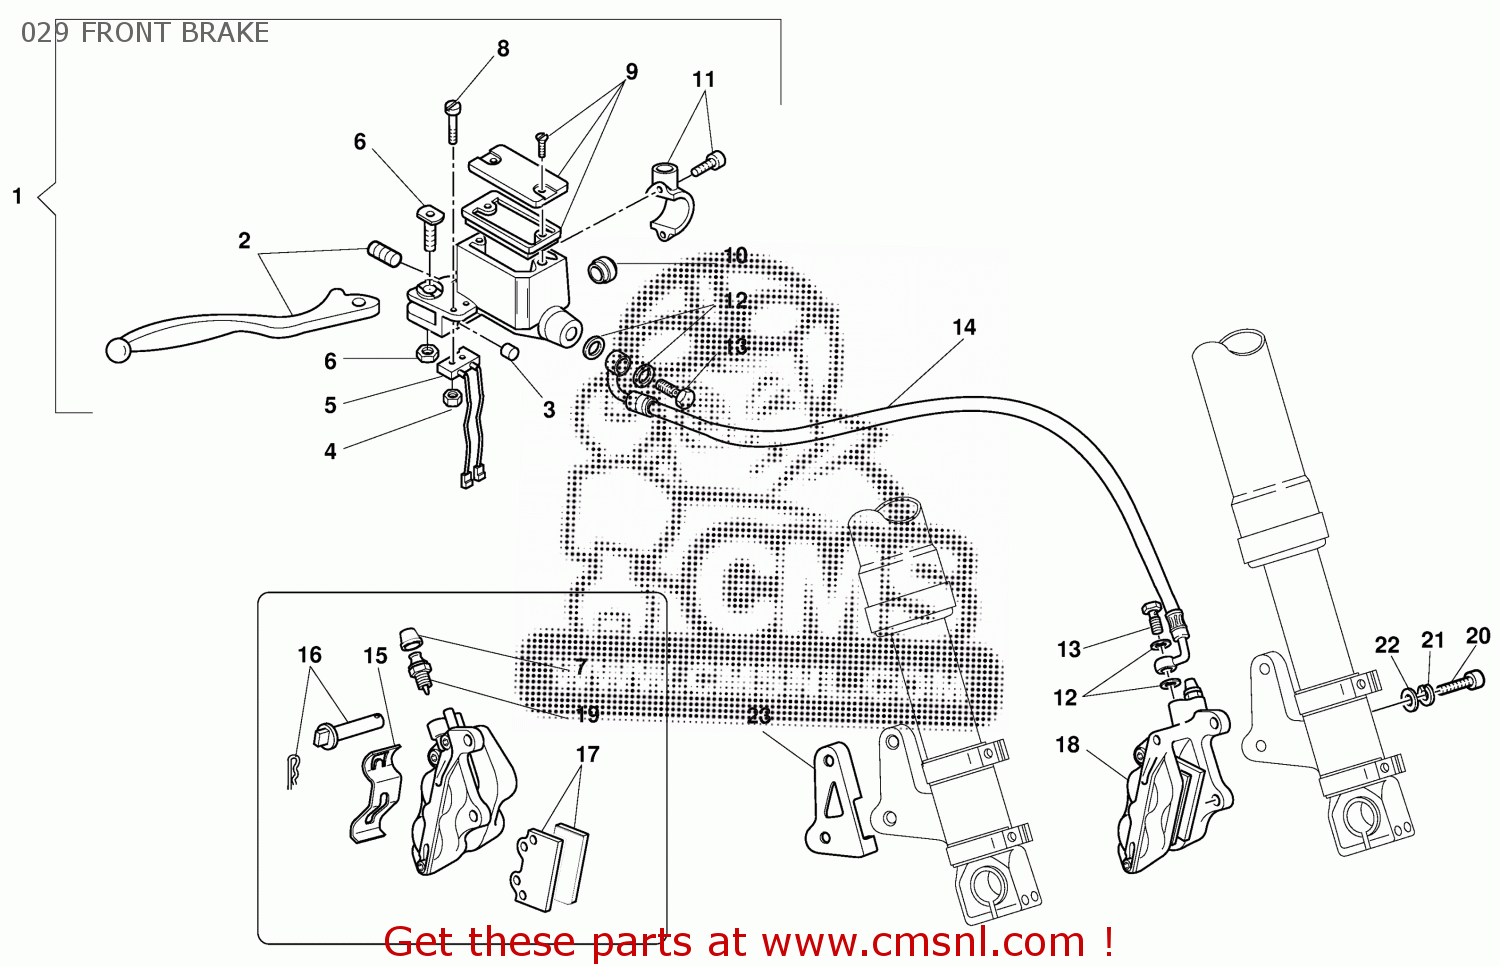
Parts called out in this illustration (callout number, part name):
1	FRONT BRAKE PUMP
2	LEVER
3	RUBBER PAD
4	NUT
5	FRONT BRAKE LIGHT SWITCH
6	BOLT, HANDLE LEVER PIVOT
7	DUST COVER
8	SCREW
9	CAP, RESERVOIR
10	WINDOW, OIL LEVEL CHECK
11	BRACKET, MASTER CYLINDER
12	COPPER GASKET 11.9X8.2X2
13	SCREW, SPECIAL
14	FRONT BRAKE HOSE
15	SPRING, PAD STOPPER
16	PAD PINS OVERHAUL KIT
17	FRONT BRAKE PADS SET
18	LEFT FRONT BRAKE CALIPER
19	BREATHER VALVE
20	SCREW
21	WASHER, SPRING
22	WASHER
23	COVER
